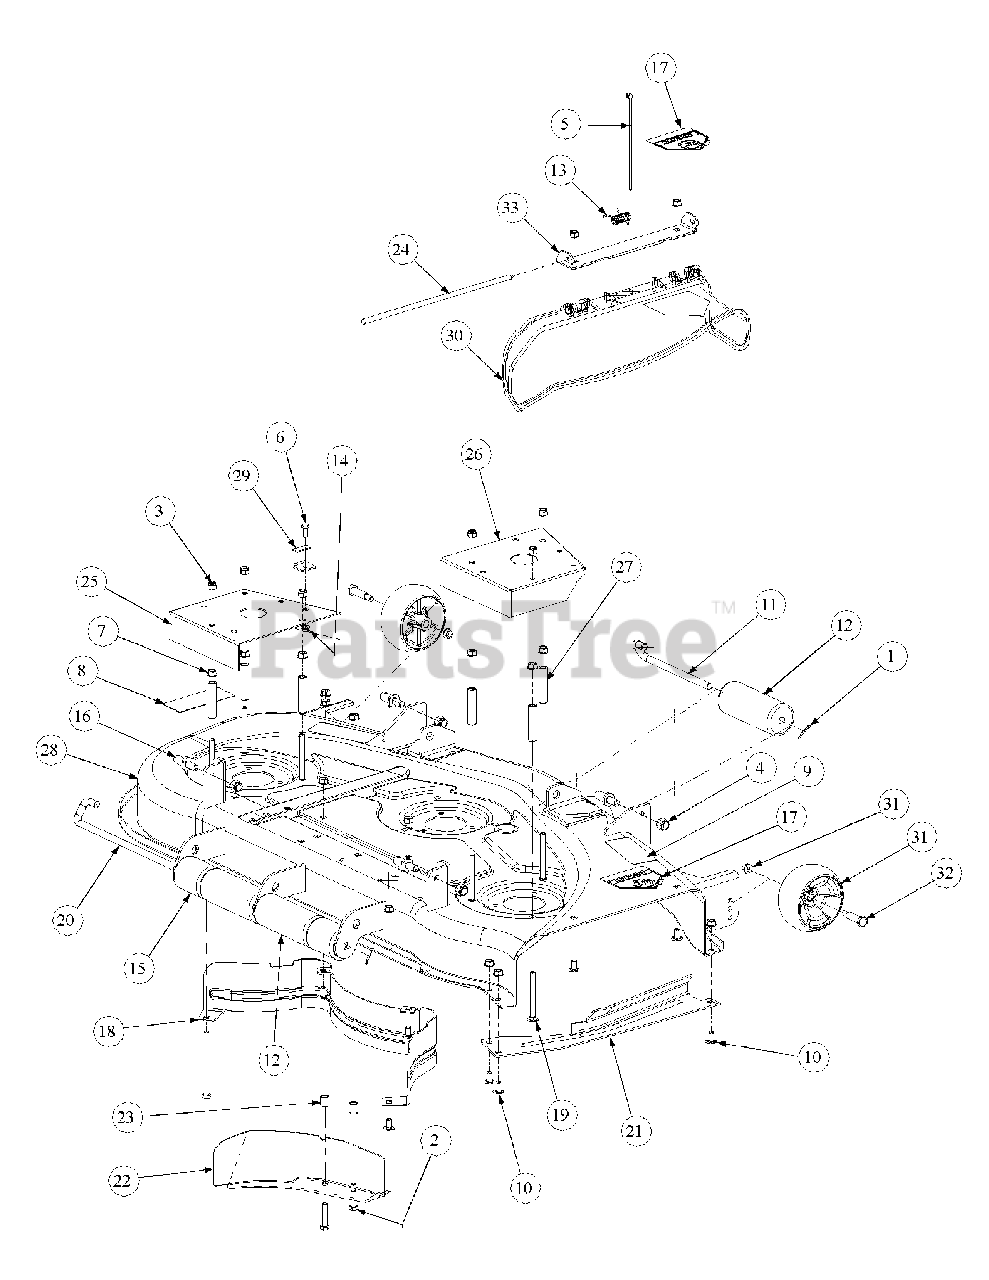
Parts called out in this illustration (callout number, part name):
1	Cotter Pin, .125 Dia x 1.0
2	Capscrew, 3/8-16 x 1-3/4
3	Nut, 3/8-16
4	Lock Nut, Nylon Insert, 1/2-13
5	Cable Tie, 3/16 x .05 x 7.4
6	Hex Cap Screw, 5/16 -18 x 3/4
7	Hex Nut Flange Lock, 3/8-16
8	Decal, Rotating Blade
9	Decal, Warning Shield Missing
10	Carriage Bolt, 3/8-16 x .75 Lg
11	Roller Pin, 1/2 Dia x 7.31 Lg
12	Front and Rear Roller
13	Torsion Spring
14	Hex Flange Lock Nut, 5/16-18
15	Short Roller
16	Pin, 5/8 Dia x 1.2 Lg
17	Decal, Danger Hands and Feet
18	48" Right Rear Inner Baffle
19	Carriage Bolt, 3/8-16 x 4.00
20	Roller Pin Rod
21	Finger Guard
22	48" Deck Baffle
23	Spacer, .385 ID x .75 OD x .875
24	Hinge Pin, .375 x 14.06
25	48" Left Hand Belt Cover
26	48" Right Hand Belt Cover
27	Spacer, .39 ID x .625 OD x 2.75
28	48" Stamped Deck
29	Tension Rod Stop Bracket
30	Deflector Chute
31	Wheel, 5.0 Dia
32	Shoulder Screw, .498 x 1.53, 3/8-16
33	Chute Mounting Bracket
